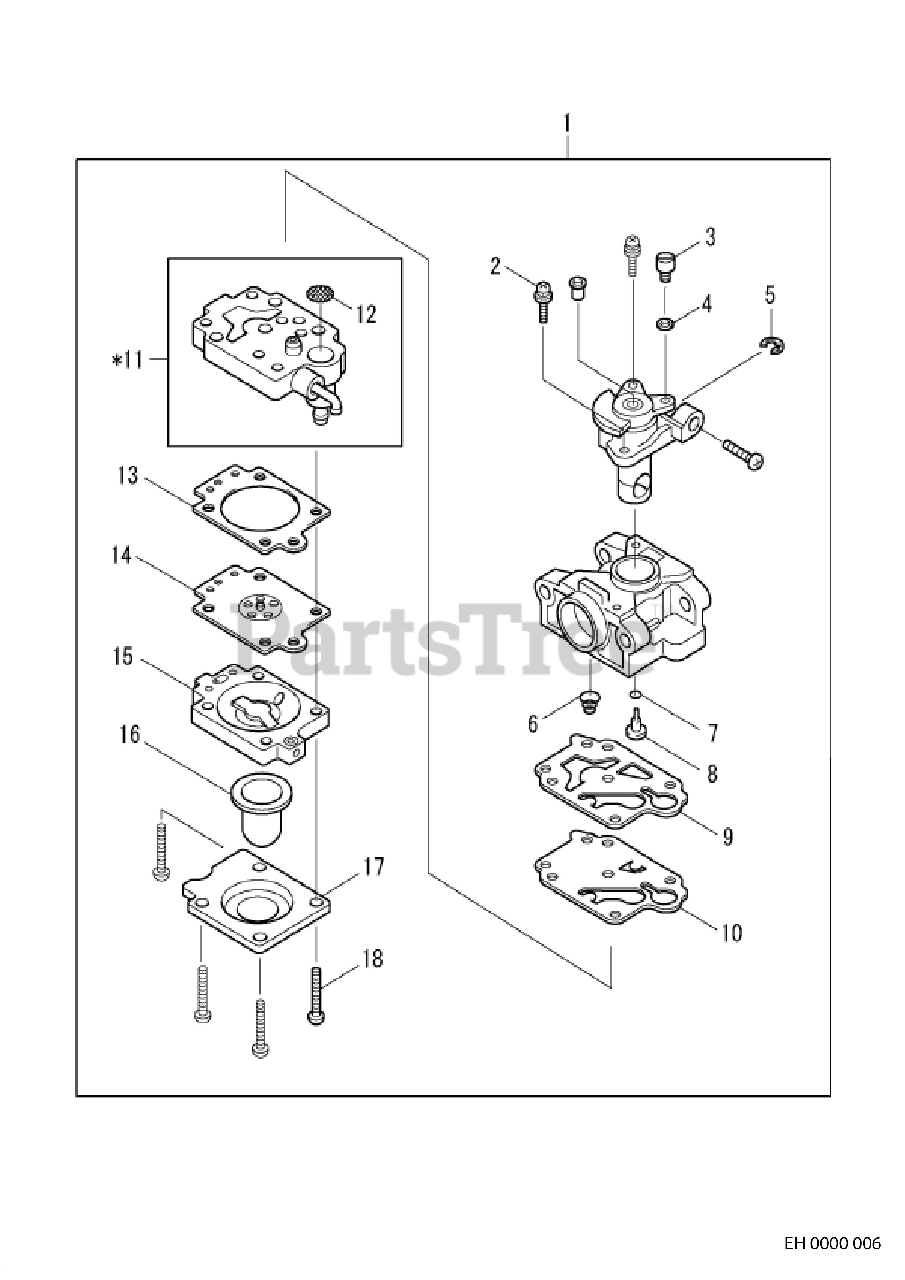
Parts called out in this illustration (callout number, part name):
3	SWIVEL
4	WASHER
5	STOP RING E-3
7	O RING - 2
8	JET
9	GASKET, PUMP
10	DIAPHRAGM, PUMP
11	PUMP BODY ASSY
12	SCREEN
13	GASKET, METERING DIAPHRAGM
14	DIAPHRAGM, METERING
15	AIR PURGE BODY
16	BULB, PURGE
17	COVER, PURGE BULB
18	SCREW - 3X24
